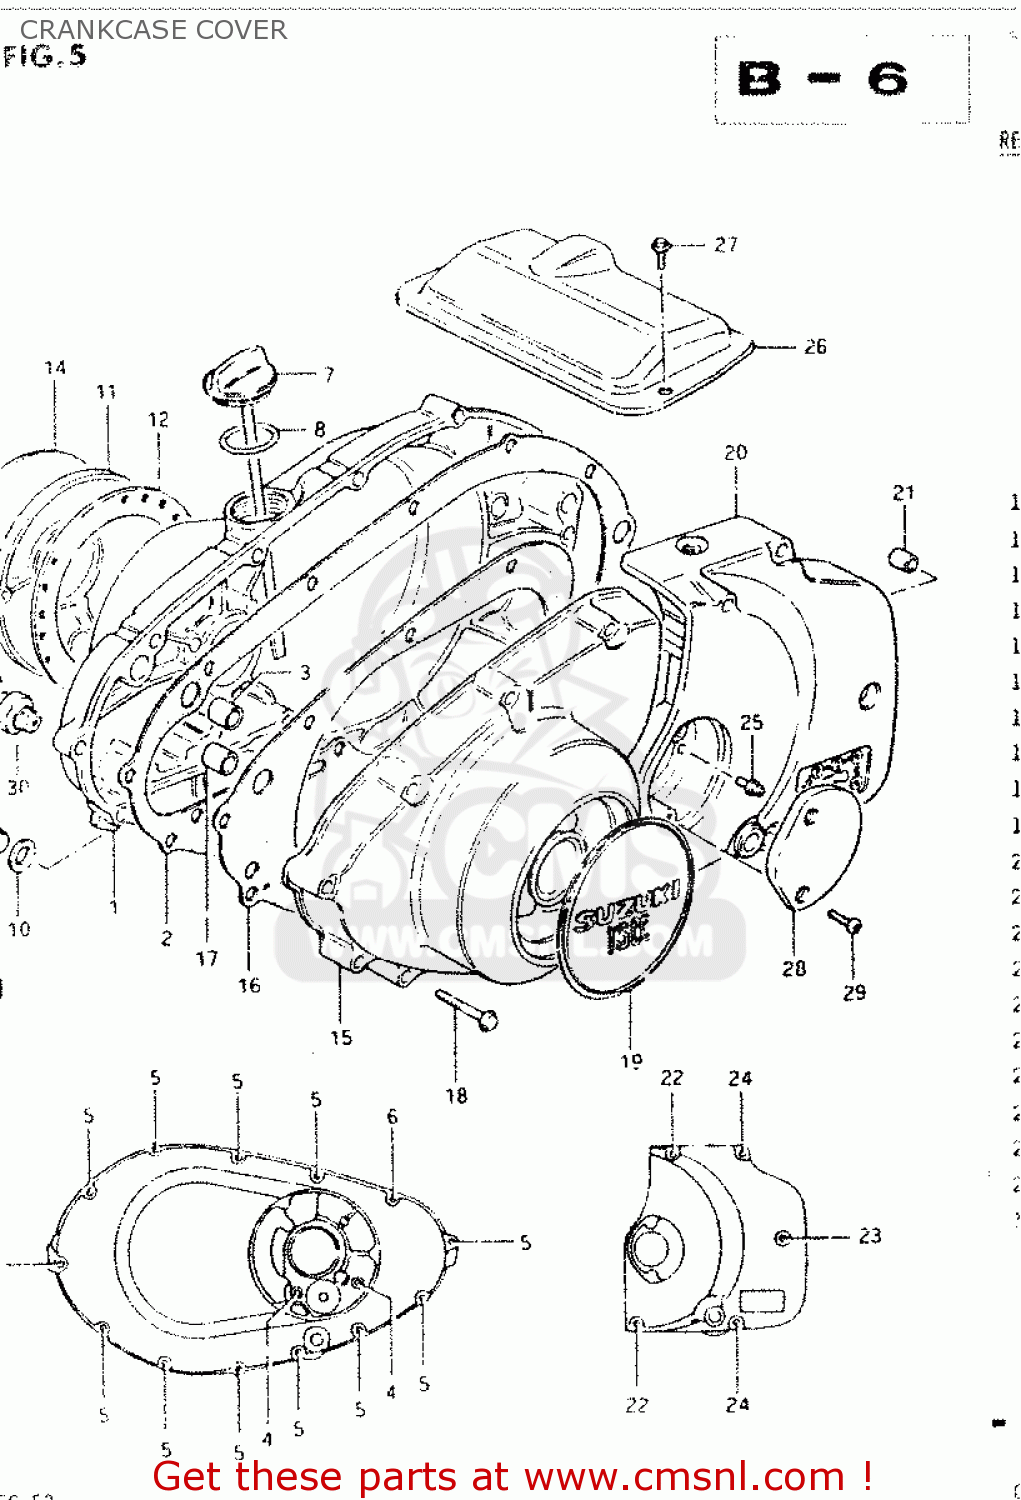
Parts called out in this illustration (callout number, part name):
1	COVER,CLUTCH
2	GASKET,CLUTCH COVER (MCA)
3	PIN
4	BOLT (6X55)
5	BOLT 6X35
6	BOLT 6X25
7	GAUGE,OIL LEVEL
8	O-RING
9	PLUG (14X12)
10	GASKET(14X19.2X2) (NAS)
11	COVER,CONTACT
12	GASKET,CONTACT (MCA)
13	BOLT 5X16
14	EMBLEM
15	COVER,MAGNETO
16	GASKET,MAGNETO COVER (MCA)
17	PIN
18	BOLT 6X35
19	EMBLEM
20	COVER, ENGINE SPROCKET
21	PIN
22	BOLT
23	BOLT 6X50
24	BOLT 6X40
25	NIPPLE
26	COVER,STARTER MOTOR
27	BOLT
28	CAP, CLUTCH RELEASE
29	SCREW
30	SWITCH ASSEMBLY
